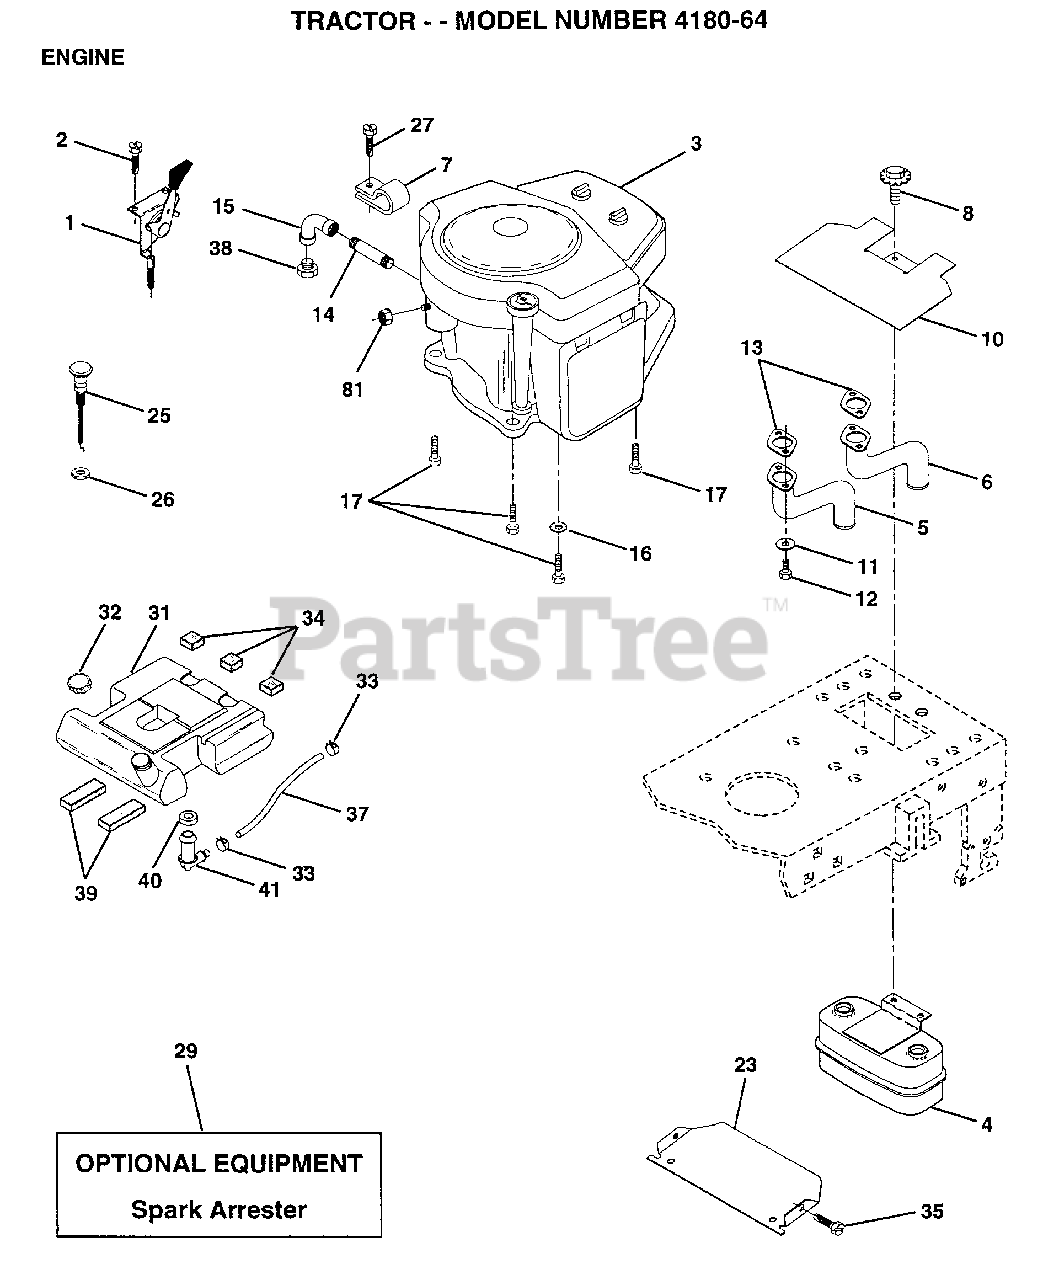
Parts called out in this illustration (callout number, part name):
2	SCREW LT
3	ENGINE, B&S
4	MUFFLER.TW.LOTONE
5	EXHAUST.B&S.18.LH
6	EXHAUST.B&S.18.RH
7	CLAMP.TUBE.DBL.EN
8	BOLT.5/16-18.UNC
10	SHIELD.HEAT.
11	LOCKWASHER
13	GASKET MUFFLER
14	PIPE NIPPLE LT
15	ELBOW
16	LOCKWASHER
17	SCREW LT
25	"CONTROL.CHOKE.51"""
26	"NUT,KEPS 3/8-24IM"
27	"SCREW-TT,10-32 FL"
31	TANK FUEL REAR
32	CAP ASM FUEL
33	HOSE CLAMP
34	PAD-SPACER LT
35	SCREW
37	FUEL LINE T
39	PAD IDLER TI
40	BUSHING OUTLET T
41	STEM.TANK.FUEL
81	NUT
